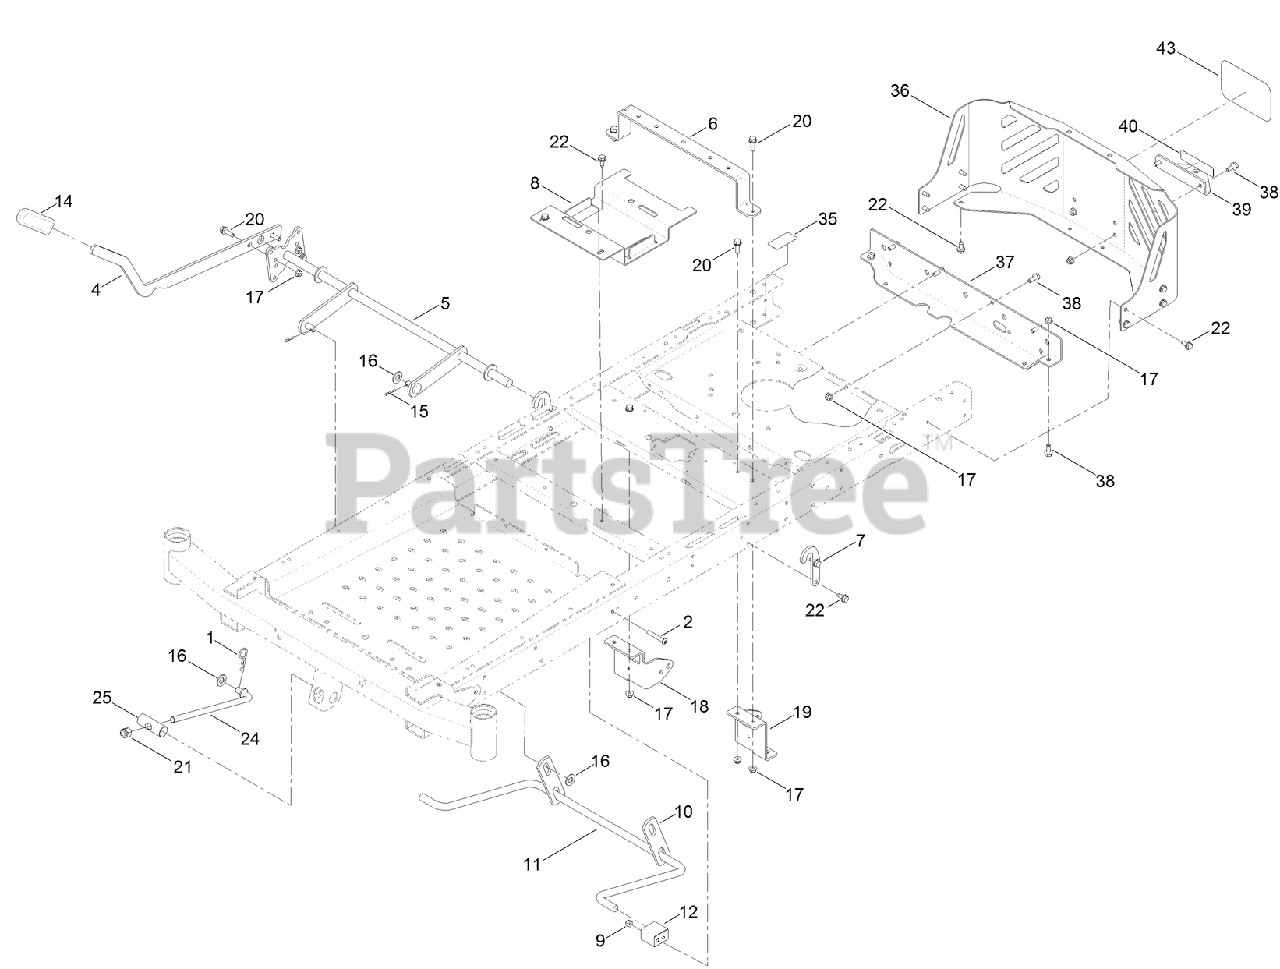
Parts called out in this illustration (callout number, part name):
1	PIN-COTTER
2	SCREW-HSBH
4	LEVER-LIFT
5	LIFT-DECK, NARROW
6	BRACE-SEAT, REAR (NARROW)
7	BRACKET-LIFT
8	BRACKET-BATTERY
9	NUT-LOCK, NI
10	LINK-LIFT
11	ARM-LIFT, REAR
12	BLOCK-PIVOT
14	GRIP-LEVER
15	PIN-COTTER
16	WASHER-FLAT
17	NUT-HF, NI
18	MOUNT-HYDRO, FRONT (RH)
19	MOUNT-HYDRO, FRONT (LH)
20	SCREW-HHF
21	NUT-HEX
22	SCREW-HWHTF
24	ROD-MOUNT, DECK
25	PIN-PIVOT
35	DECAL-BYPASS
36	GUARD-ENGINE, NARROW
37	CROSSMEMBER-REAR, NARROW
38	SCREW-HHF
39	BRACKET-HITCH
43	DECAL
